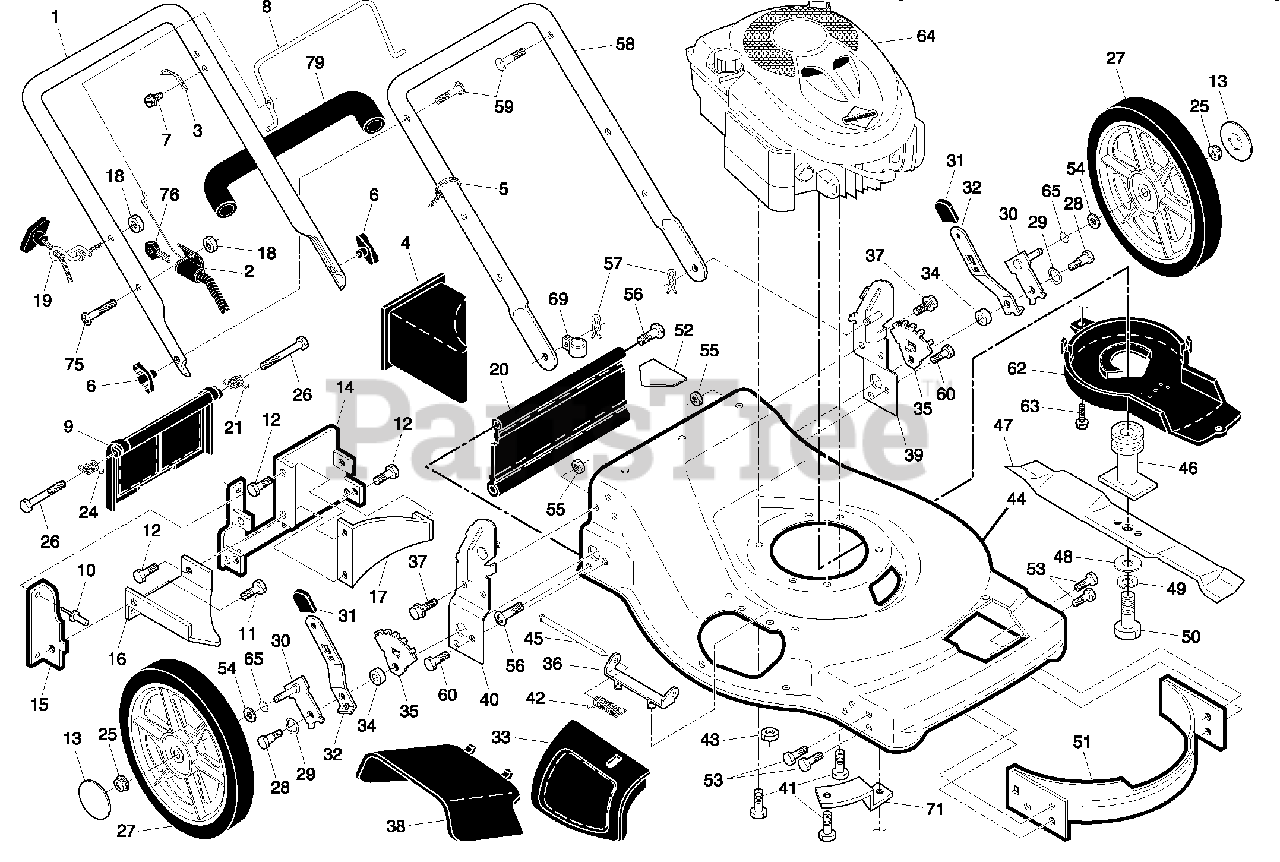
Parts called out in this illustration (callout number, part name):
1	Upper Handle Assembly
2	Key Start Switch
3	Bracket, Upstop
4	Mulcher Plug
5	Wire Tie
6	Handle Knob
7	Screw
8	Control Bar
9	Rear Door Assembly
10	Pop Rivet
11	Screw, Self-Tapping #10-24 x 5/8
12	Screw, Hex Hex Head, Sems 1/4-20 x 1/2
13	Hubcap
14	Back Plate
15	Side Baffle
16	Discharge Baffle
17	Rear Baffle
18	Keps Locknut 1/4-20
19	Rope Guide
20	Rear Skirt
21	Spring, Rear Door, LH
24	Spring, Rear Door, RH
25	Nut, Hex, Flanged
26	Bolt, Rear Door
27	Wheel & Tire Assembly, Rear
28	Bolt, Shoulder 3/8-16 x 1
29	Washer, Curved, Cylindrical
30	Axle Arm Assembly
31	Selector Knob
32	Selector Spring
33	Mulcher Door
34	Spacer
35	Wheel Adjusting Bracket
36	Hinge Bracket Assembly
37	Screw, Sems, Thread Cutting 5/16-18 x 3/4
38	Discharge Deflector
39	Handle Bracket Assembly, LH
40	Handle Bracket Assembly, RH
41	Screw, Hex Head, Threaded, Rolled 3/8-16 x 1-1/8
42	Spring, Torsion
43	Nut, Hex, Nylock
44	Kit, Mower Housing
45	Rod, Hinge
46	Blade Adapter / Pulley
47	Blade, 22"
48	Washer, Hardened
49	Washer, Helical
50	Screw, Machine, Hex Head 3/8-24 x 1-3/8 Grade 8
51	Kit, Front Baffle
52	Danger Decal
53	Screw, Serrated, TT 1/4-20
54	Washer, Flat
55	Nut, Hex 3/8-16
56	Hinge Screw 1/4-20 x 1-1/4
57	Hairpin Cotter
58	Lower Handle
59	Handle Bolt
60	Bolt, Hex Head 3/8-16 x 3/4
62	Debris Shield
63	Screw, Debris Shield
65	O-Ring
69	Clip, Cable
71	Mounting Bracket, Debris Shield
75	Screw
76	Key
79	Grip, Foam
79	Operator's Manual, English
79	Operator's Manual, French
79	Repair Parts Manual
